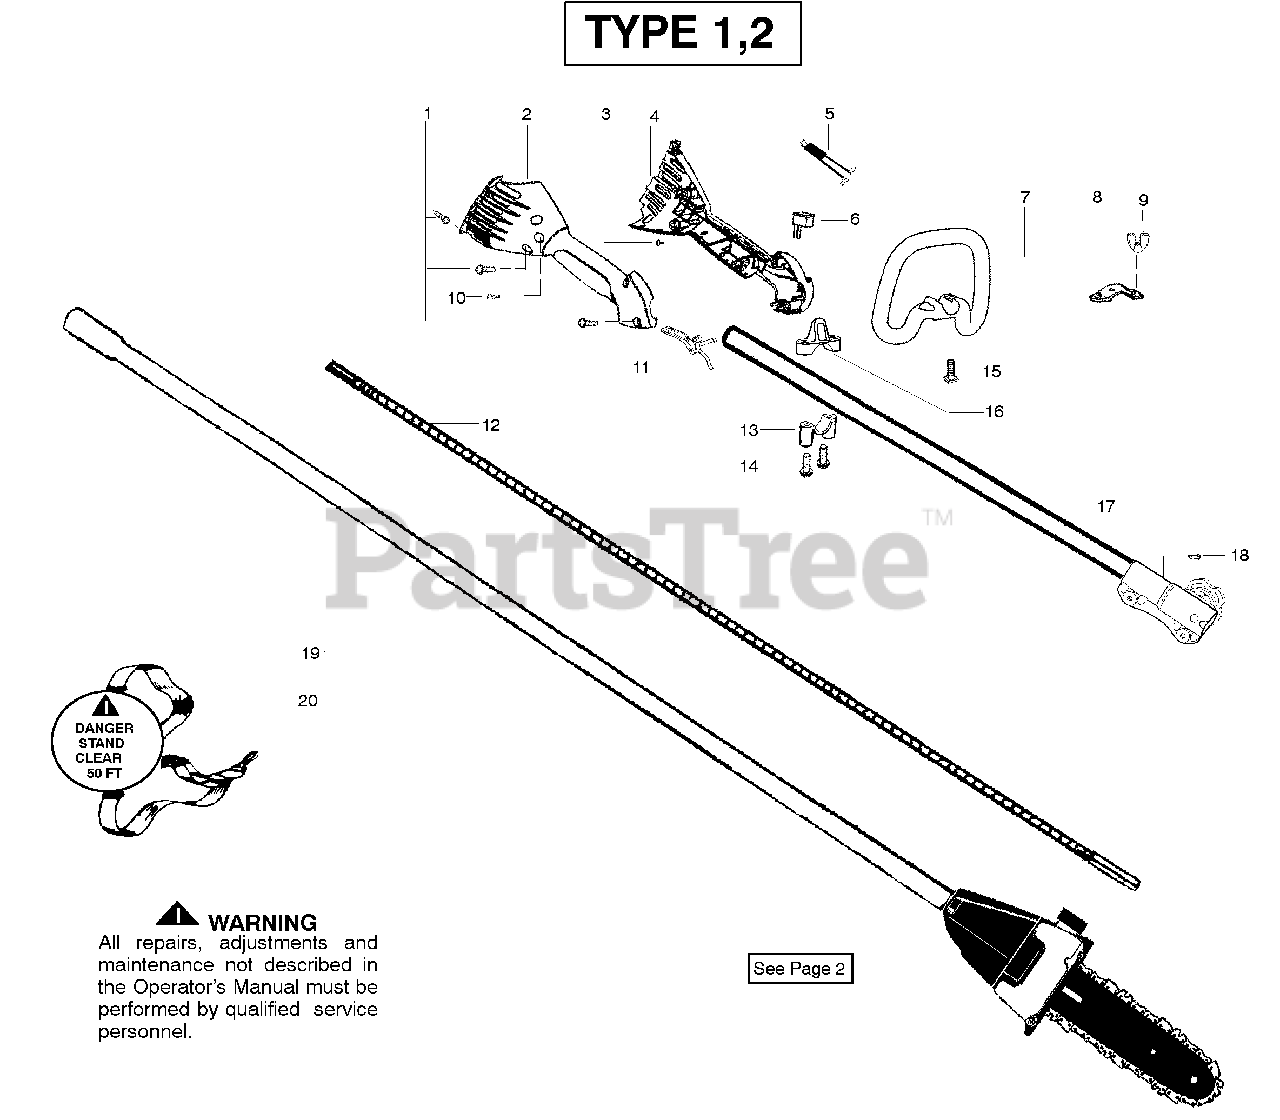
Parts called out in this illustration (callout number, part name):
2	Hsg.-Throttle right
3	Screw-Cable Ret.
4	Hsg.-Throttle left
5	Assy-Wire
6	Kit-Switch
7	Assy-Handle
8	Clamp-Handle
9	Wingnut
10	Screw-Align
11	Trigger-Throttle
12	Flex-Lower
13	Clamp-Lower
16	Clamp-Upper
17	Kit-Upper Shaft
19	Assy-Driveshaft
20	Assy-Shoulder Strap
